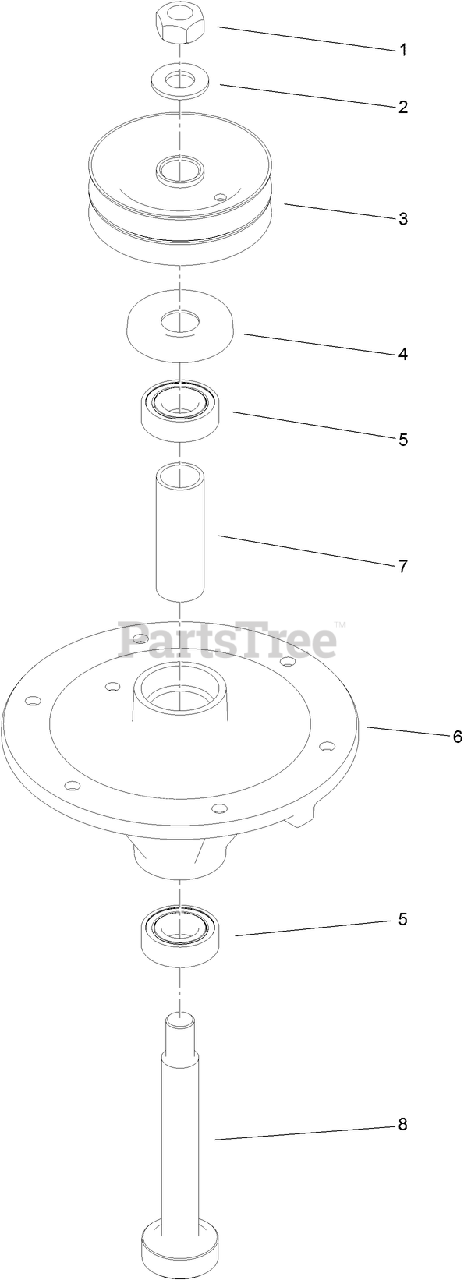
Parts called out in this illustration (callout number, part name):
1	NUT-HEX
2	WASHER
3	PULLEY ASM
4	SHIELD-BEARING
5	BEARING-BALL
6	HOUSING-SPINDLE
7	SPACER-BEARING
8	SHAFT-SPINDLE
